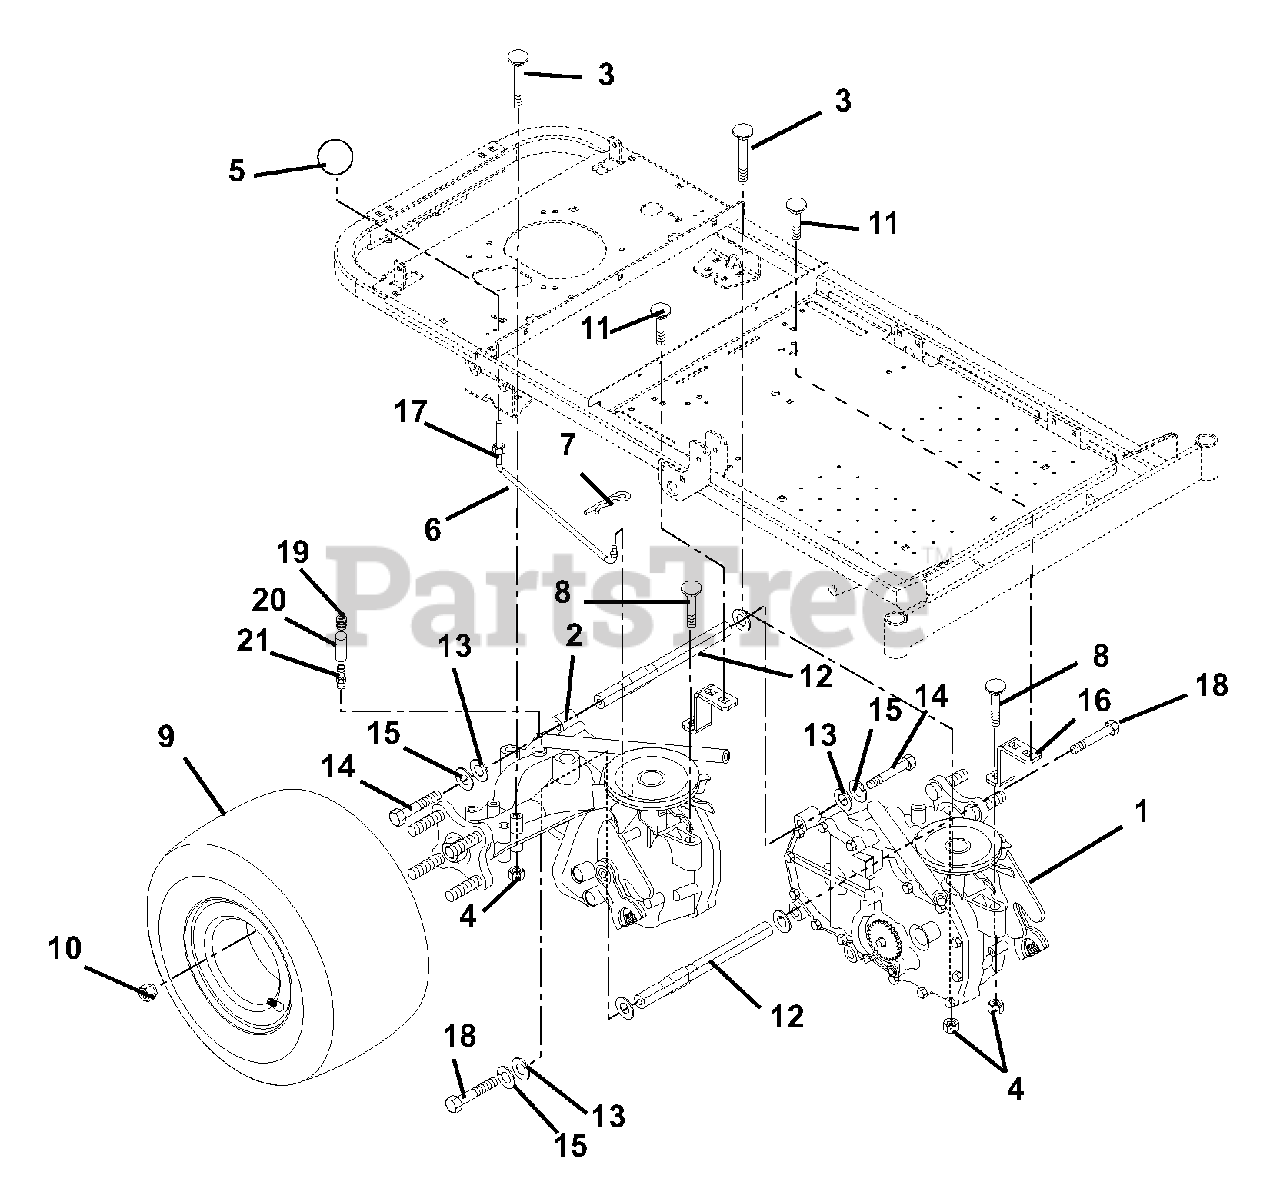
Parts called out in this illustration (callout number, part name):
1	EZT,LH TRANSAXLE-HYDROGEAR
2	EZT,RH TRANSAXLE-HYDROGEAR
3	BLT-RDHDSQSHNK.31-18X2.75G2YWZ
4	@NUT-LK-NYL-FLG .31-18 YWZC
6	ROD, DUMP EZT
7	PIN-HAIR, ENDRIES #25 YWZC
8	@BLT-RDHDSQNK .31-18X2.25 G5YZ
9	ASSY-TIRE 8.5X18 2PLY
10	NUT-LUG .50-20 YWZC
11	@BLT-RDHDSQNK .31-18X1.00 G5YZ
13	@WSHR-FL-STL.344X.688X.065YWZC
14	@BLT-HEX .31-18X2.50 GR5 YWZC
15	@WSHR-LK .31X.078 REG YWZC
16	TORQUE STRAP
17	@NUT-HEX .25-20 YWZC
18	@BLT-HEX .31-18X2.00 GR5 YWZC
19	CAP-VENT .50
20	HOSE - VENT
21	FTG-STR .50 O-RING
